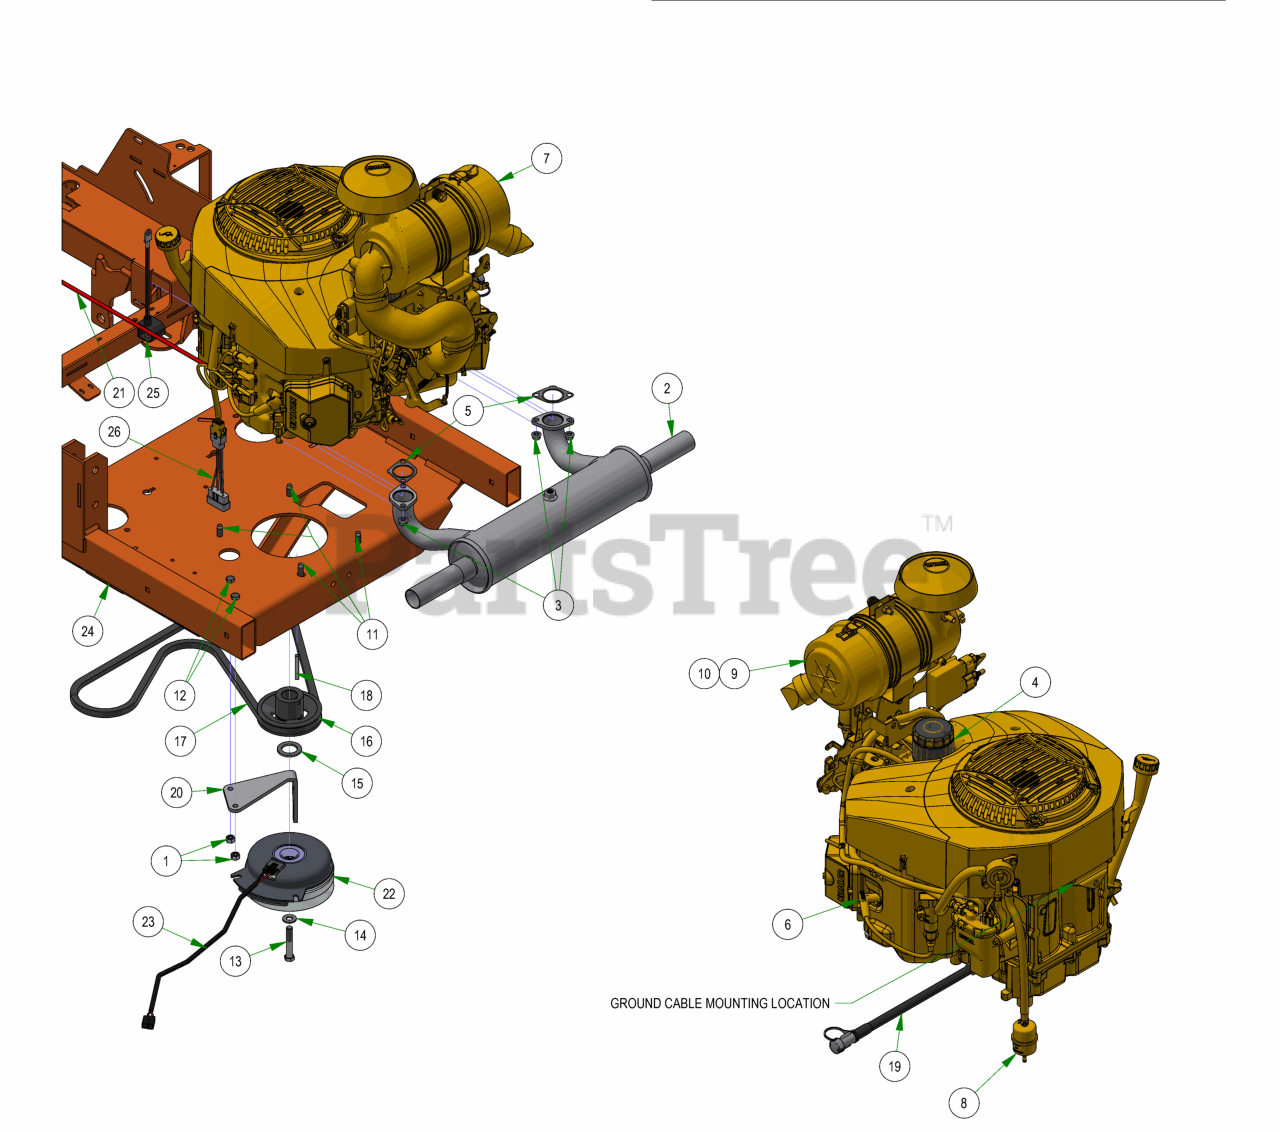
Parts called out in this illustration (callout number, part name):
1	3/8-16 HEX NUT ZINC
2	2022 Kohler ECV-980 EFI Exhaust
3	M8 Nut Connects the 015-1012-00 and the 015-8240-00
4	Kohler ECV/ECH980 OIL FILTER
5	ECV/ECH 980 MUFFLER GASKET
6	Spark Plug - Kohler ECV/ECH 980
7	Kohler ECV980
8	Universal Inline Fuel Filter
9	Canister Air Filter- Outer
10	Canister Air Filter- Inner
11	3/8-16 X 1-1/8HEX WASHER UNSLOT SERRATED (TRI-LOB) TRS
12	3/8-16 X 1-1/4 HEX CAP SCREW (GR.5) ZINC
13	7/16-20 X 2-1/2 HEX Bolt GR 8 W/ Patch
14	3/8 FLAT WASHER USS (1" OD) ZINC
15	1.140 ID X 1.750 OD X .132 THICK FLAT WASHER PLAIN
16	4 3/4 Motor Pulley
17	2019 Rogue Pump Belt 68"
18	1/4 X 2 SQ MACHINERY KEY 1018 STL PLAIN
19	Kohler 980 Oil Drain
20	PTO Engager Holder
21	24" Red Battery Cable
22	Clutch Assembly
23	Clutch Pigtail
24	2023 Rogue Frame - Painted
25	Starter Cable
26	2019 Harness Adaptor - Yamaha/Kohler EFI
